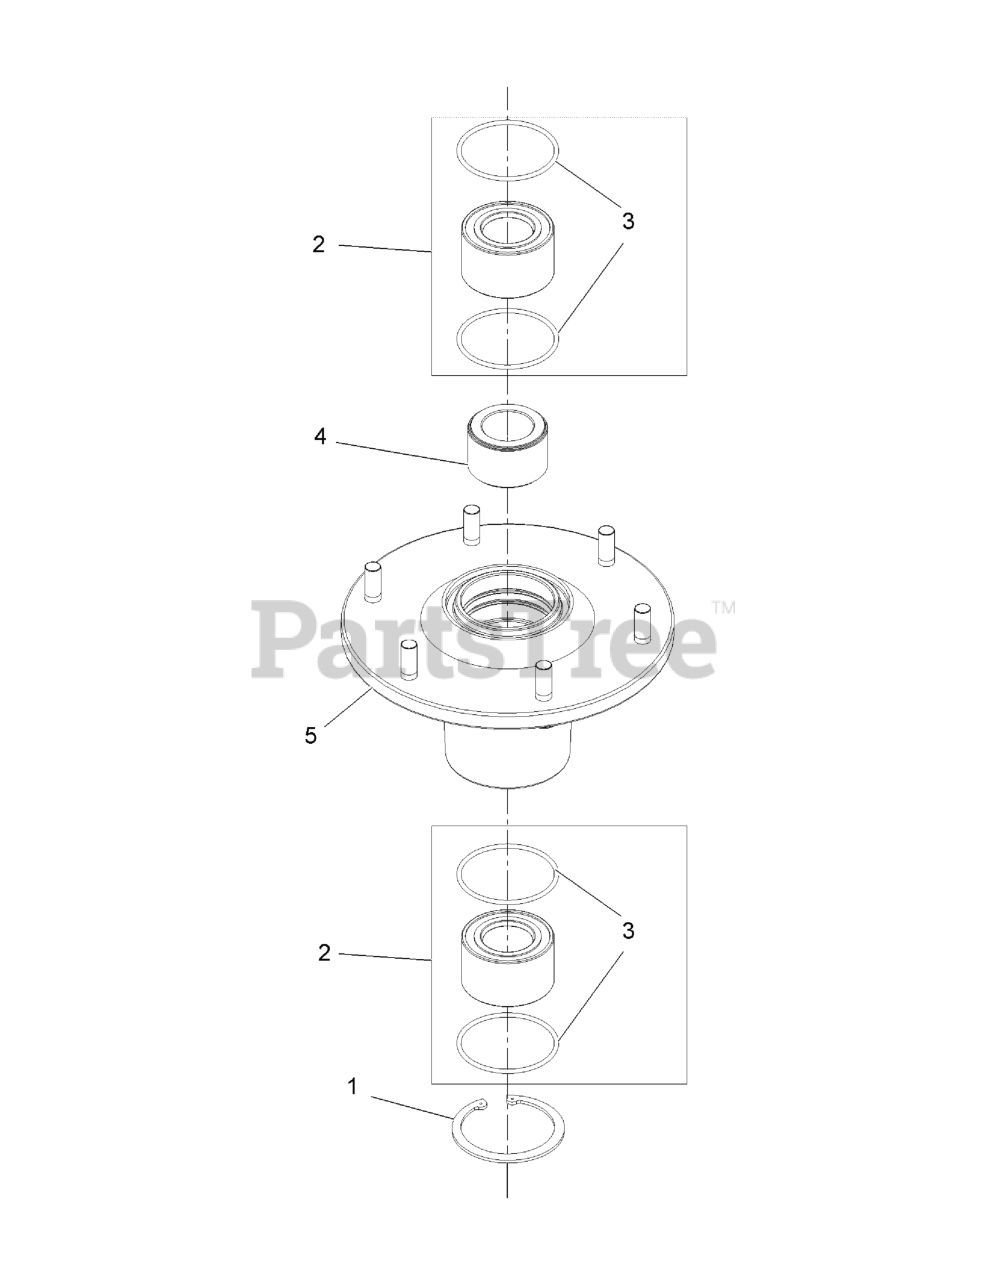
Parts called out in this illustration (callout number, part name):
1	RING-RETAINING
2	ASM, BEARING W/ORINGS
4	SPACER,BEARING
5	ASM,HOUSING W/STUDS
